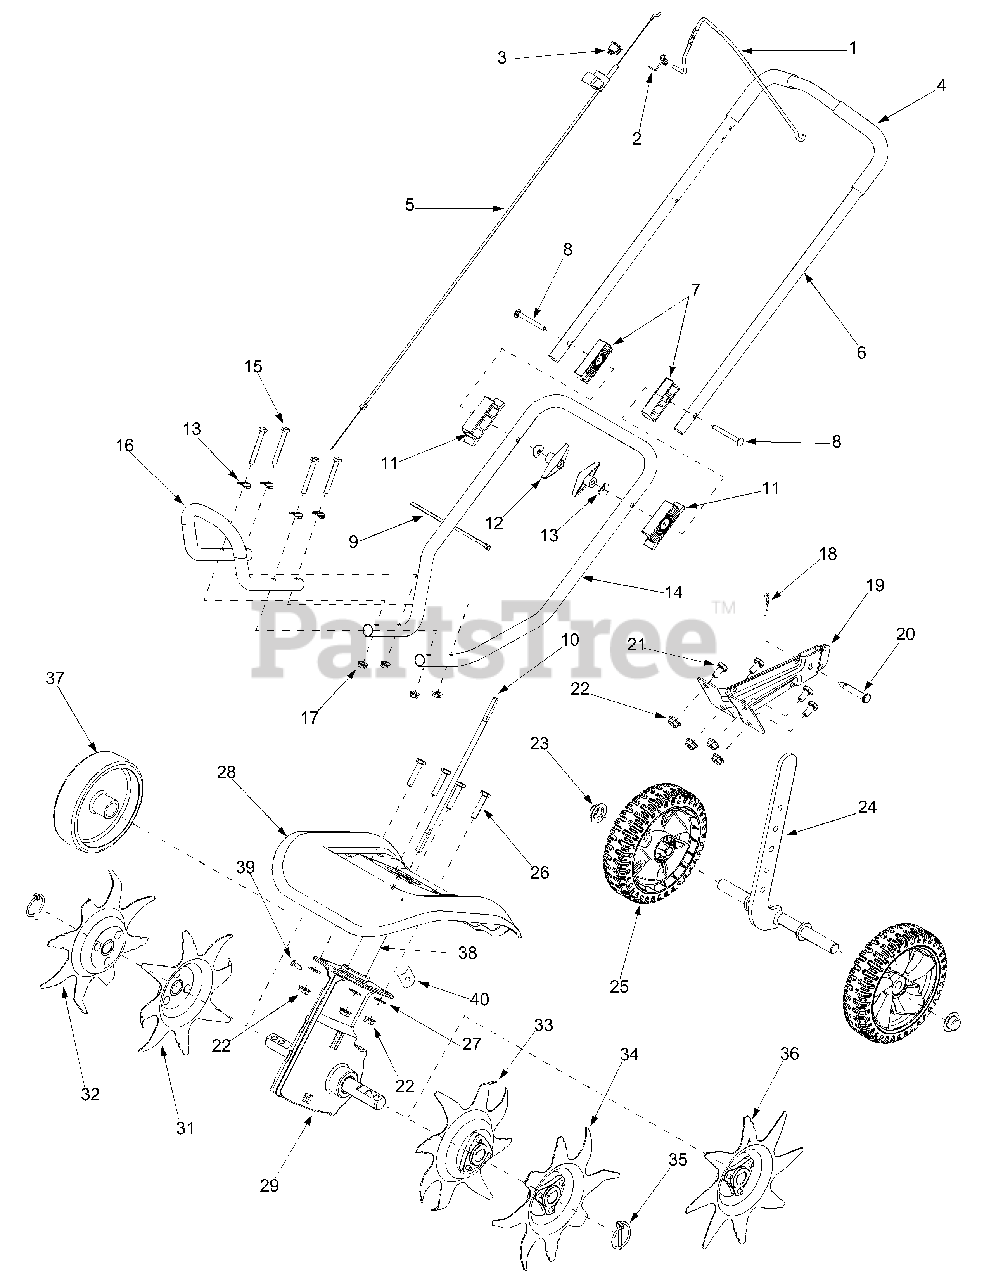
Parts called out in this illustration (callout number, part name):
1	Throttle Control
2	Torsion Spring
3	On/Off Switch
4	Foam Grip
5	Throttle Cable
6	Upper Handle
7	Upper Handle Connector
8	Carriage Bolt 5/16-18 x 3.0
9	Cable Tie
10	Drive Shaft
11	Lower Handle Connector
12	Wing Knob 5/16-18
13	Shoulder Washer .320 ID x .93 OD
14	Lower Handle
15	Hex Cap Screw 5/16-18 x 2.25
16	Front Handle
17	Flange Lock Nut 5/16-18
18	Cotter Pin
19	Tailpiece Bracket Assembly
20	Clevis Pin
21	Hex Cap Screw 1/4-20 x .50
22	Hex Lock Nut 1/4-20
23	Cap Push
24	Wheel Support Bracket Assembly
25	Wheel 7.0
26	Hex Cap Screw 1/4-20 x 1.75
27	Flat Washer .271 ID x .630 OD
28	Tine Shield
29	Gearbox
31	Inner Tine
32	Outer Tine
33	Inner Tine
34	Outer Tine
35	Click Pin
36	Edger Tine
37	Edger Wheel 5.0
38	Drive Shaft Housing
39	Gearbox Antirotation Screw
40	Retainer Sleeve
